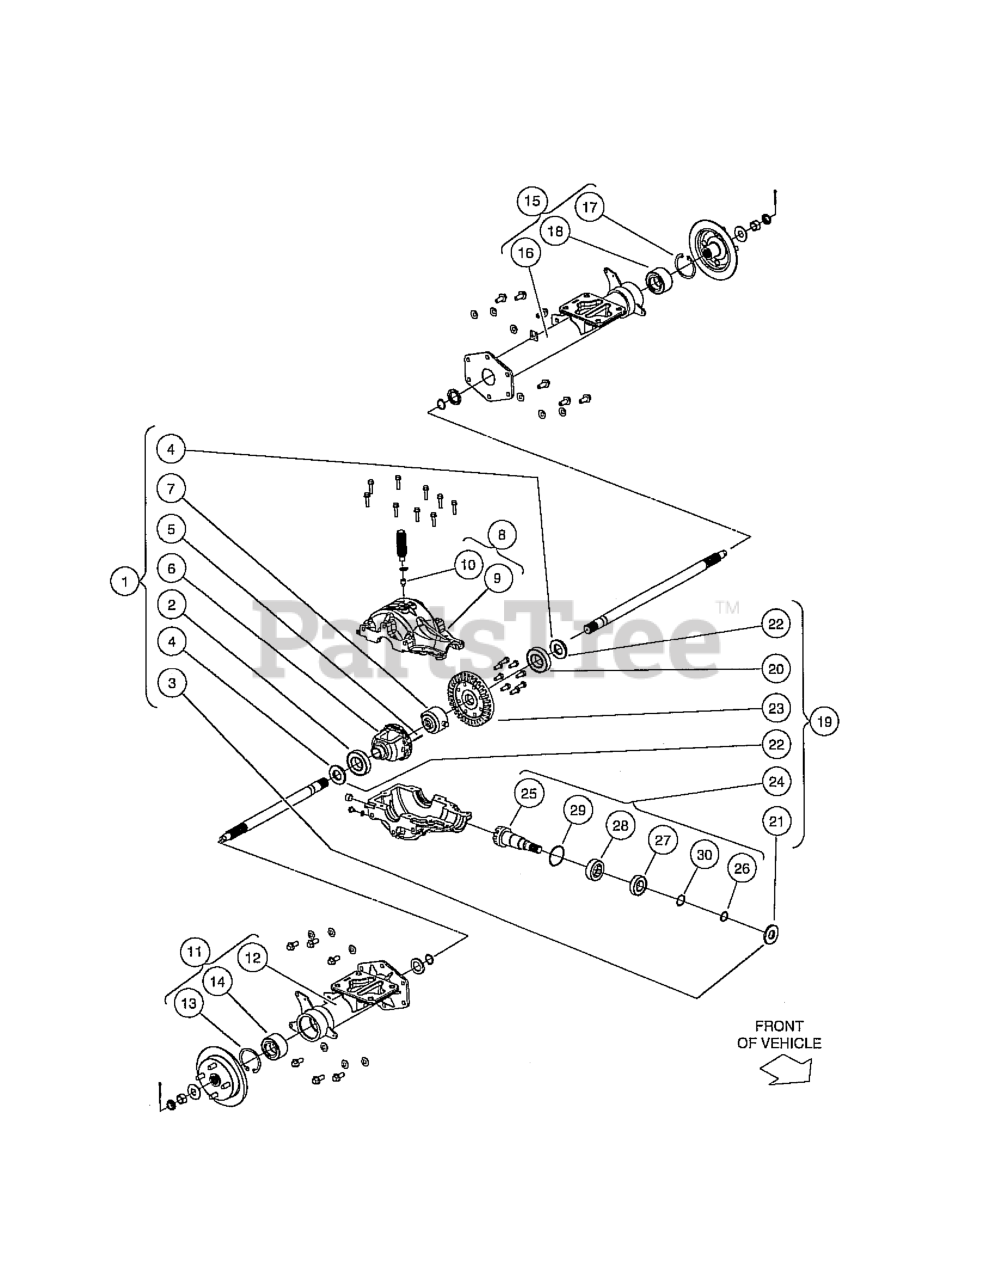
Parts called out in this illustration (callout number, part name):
1	ASM-DIFFERENTIAL & CARRIER
2	BEARING, BALL, 6208 C3
3	SEAL, DUAL LIP 25X 62X 7TC
4	SEAL, DUAL LIP 30X 62X 8TC
5	PIN, DOWEL, 4 X 35
8	ASM-GEARCASE-UPPER
10	VENT, TOP, UPPER HOUSING
11	ASM-AXLE TUBE
13	RING, RETAINING, INTERNAL
14	BEARING, DAC
15	ASM-AXLE TUBE LH
17	RING, RETAINING, INTERNAL
18	BEARING, DAC
19	KIT-REAR AXLE GEAR REPAIR
20	BEARING, BALL, 6208 C3
21	SEAL, DUAL LIP 25X 62X 7TC
22	SEAL, DUAL LIP 30X 62X 8TC
26	RING, RETAINING EXTERNAL
27	BEARING, BALL 6206R
28	BEARING, NEEDLE, DRAWN SHELL
29	WASHER, 2.625 X 2.367 X .06
30	SHIM, 1.50 X 1.189 X .008
